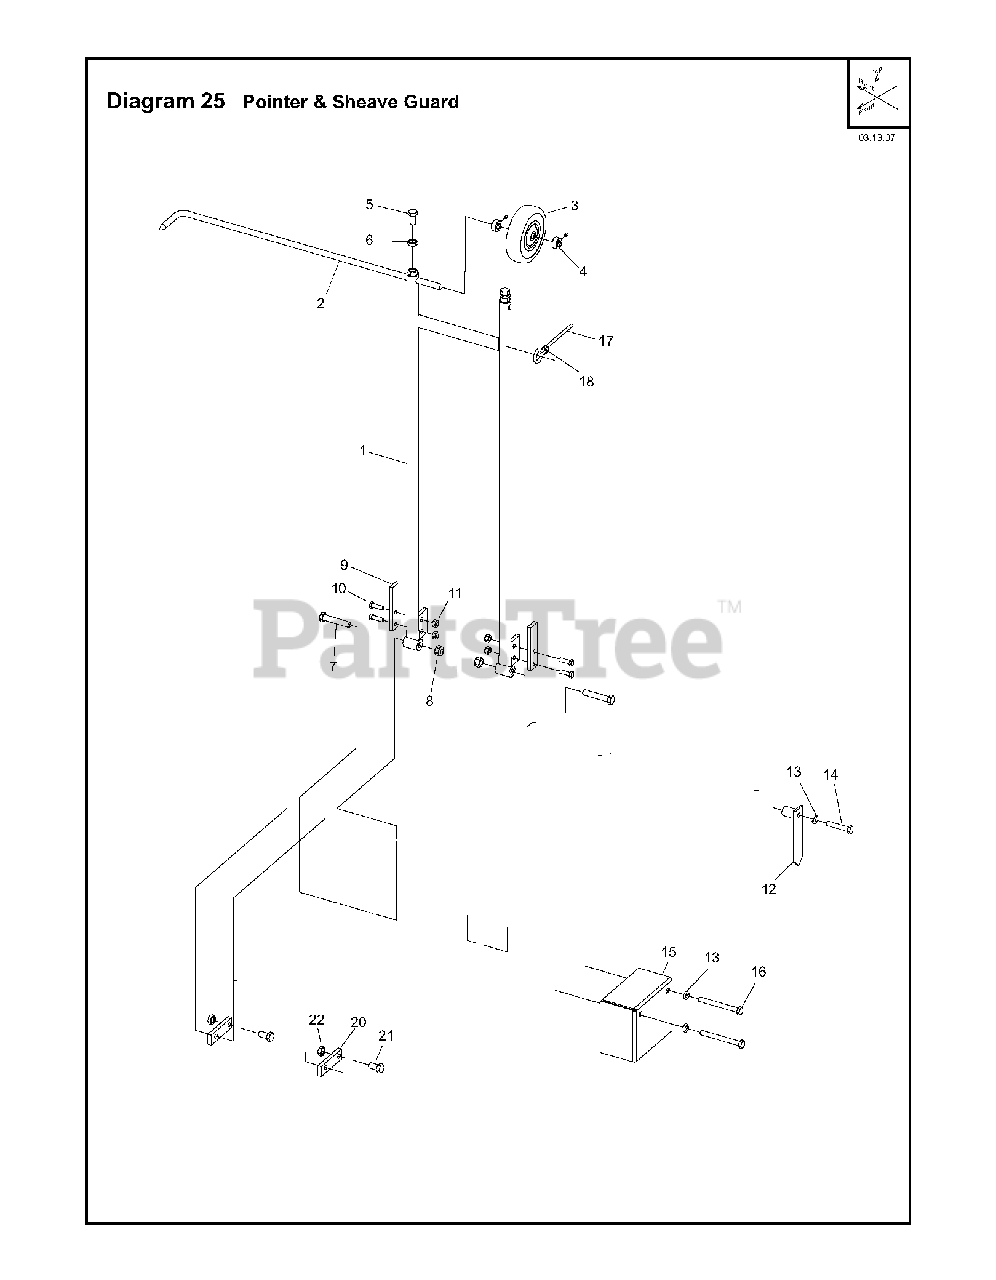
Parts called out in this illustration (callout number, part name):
5	HHCS. M12 x 1.75 x 25 DIN933ZP
7	HHCS. M12 x 1.75 x 65 DIN931ZP
8	LOCKNUT. FIBER M12 DIN 985 Z/P
11	HEXAGON LOCKING NUT
13	LOCKWASHER. SPLIT M10
14	HHCS. M10 x 1.5 x 50 DIN933 ZP
16	HHCS. M10 x 1.5 x 110 DIN931ZP
17	SASH CORD. 1/4 DIA #85 X 1200
20	GRILL/LENS.ASM.DL.HUSQ
21	HHCS. M12 x 1.75 x 30 DIN933ZP
